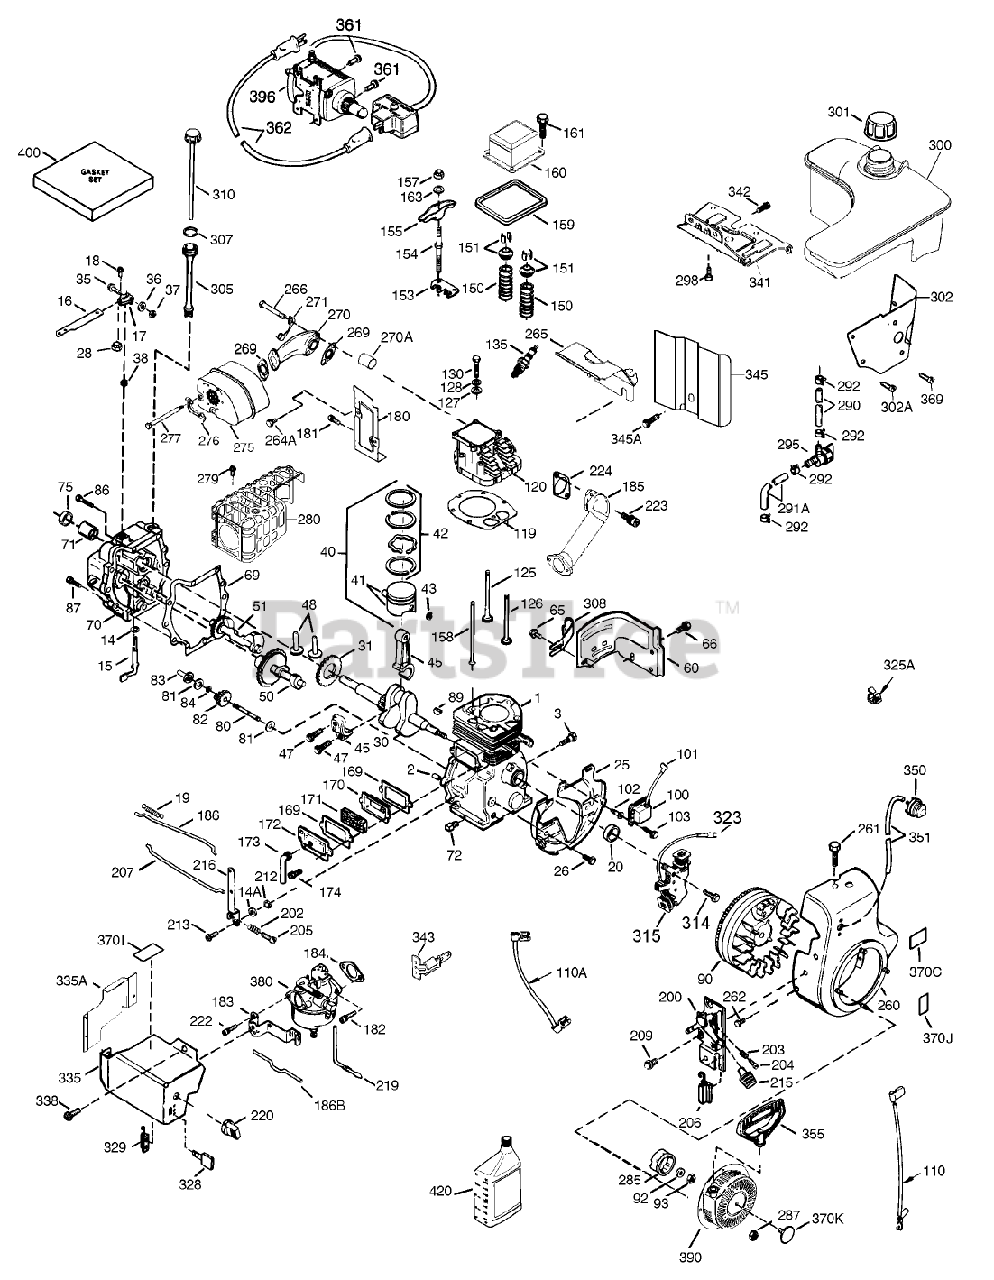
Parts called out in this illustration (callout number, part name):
1	Cylinder (Incl. 2, 20, 72 80)
2	Pin-Dowel
3	Screw (1/4-20x1/2)
14	Washer-Flat
14A	Washer
15	Governor Rod (Incl. Ref.#14 38)
16	Governor Lever
17	Clamp-Lever, Governor
18	Screw (T-15, 8-32x7/16)
19	Throttle Spring
20	Seal-Oil
25	Baffle-Housing, Blower
26	Screw (1/4-20x19/32)
28	Nut-Lock
30	Crankshaft
31	Counterbalance Gear
35	Screw
36	Washer-Lock
37	Nut-Lock
38	Ring-Retaining
40	Piston Pin and Ring ASM (STD)
40	Piston Pin and Ring ASM (.010)
40	Piston Pin and Ring ASM (.020)
41	Piston Pin Ass-y(Std.)(Incl. 43)
41	Piston Pin Ass-y (.010" OS)(Incl. 43)
41	Piston Pin Ass-y.(.020" OS)(Incl. 43)
42	Ring Set (STD)
42	Ring Set (.010)
42	Ring Set (.020)
43	Retaining Ring-Piston Pin
45	Connecting Rod ASM (Incl. Ref. #47)
47	Bolt-Rod, Connecting
48	Lifter-Valve
50	Camshaft
51	Counterbalance Weight
60	Extension-Housing, Blower
65	Screw (10-24 x 9/16)
66	Screw
69	55072/75/86/89 TWO
70	Cylinder Cover (Incl. Ref. #14, 15, 38, 71, 75)
71	2025A77 WIZARD ROTA
72	Plug-Drain, Oil (SQH 1/4-18)
75	Seal-Oil
80	Governor Shaft
81	Washer
82	Gear-Asm Governor
83	Governor Spool
84	Ring-Retaining
86	Screw (1/4-20x1-3/16)
87	Screw (1/4-20x1-11/16)
89	Key-Flywheel
90	Flywheel ASM
92	Washer-Belleville
93	Nut-Flywheel
100	Solid State ASM
101	Cover-Spark Plug
102	Stud-Mounting, Solid State
103	Screw (T-15, 10-24 x 15/16)
110	Wire-Ground
110A	Wire-Ground
119	Cylinder Head Gasket
120	Cylinder Head
125	Valve-Exhaust (STD)
125	Valve-Exhaust (1/32)
126	Valve-Intake (STD)
126	Intake Valve (1/32)
127	Washer-Flat
128	Washer-Belleville
130	Screw (5/16-18 X 2-1/2)
135	Spark Plug-Resistor (R N 4C)
150	Spring-Valve
151	Keeper-Spring, Valve
153	Guide-Rod, Push
154	Stud-Arm, Rocker
155	Arm-Rocker
157	Nut-Jam
158	Rod-Push
159	Gasket-Cover, Rocker Arm
160	Cover-Arm, Rocker
161	Screw
163	Washer
169	Gasket-Cover, Valve
170	Body-Breather
171	Element-Breather
172	Cover-Valve
173	Tube-Breather
174	Screw
180	Extension-Housing, Blower
181	Screw (10-24 x 9/16)
182	Screw (T-30, 1/4-20 X 27-32)
183	Bracket-Choke
184	Gasket-Carburetor To Intake Pipe
185	Pipe-Intake
186	Governor Link
186B	Spring-Choke
200	Bracket-Control (Incl. Ref. #203, 204 and 206)
202	Compression Spring
203	Spring-Compression
204	Screw (T-10, 5-40x7/16)
205	Screw
206	Terminal
207	Choke Link
209	Screw (10-32 x 1/2)
212	Bushing
213	Screw
215	Knob-Control
216	Lever-Adjusting
219	Rod-Choke
220	Knob-Control
222	Screw (10-32 x 1/2)
223	Screw (T-30, 5/16-18 X 7/8)
224	Gasket-Pipe
260	Blower Housing
261	Screw (1/4-20 X 5/8)
262	Screw
264A	Screw
265	Cover-Head, Cylinder
266	Screw (5/16-18 X 1-9/32)
269	Gasket-Manifold, Exhaust
270	55107 SNWTHWR ATTCH
270A	Liner-Port, Exhaust
271	Plate-Locking
275	Muffler
276	Locking Plate
277	Screw (5/16-18 X 4-1/2)
279	Screw
280	Cylinder (Incl. 2, 20 150)
285	Cup-Starter
287	Nut and Lock Washer (1/4-28)
290	Line-Fuel
291A	Line-Fuel (8.62)
292	Clamp-Line, Fuel
295	Valve-Shut Off, Fuel
298	Screw (1/4-15x7/8)
300	Fuel Tank (Incl. 292 and 301)
301	Cap-Fuel
302	Extension-Tank, Fuel
302A	Screw (10-32 x 1/2)
305	Tube-Fill, Oil
307	O-Ring
308	Clip-Tube, Fill
310	Dipstick
314	Screw (1/4-20 x 3/4)
315	Coil-Alternator, 18 Watt (Includes 323)
323	Terminal
328	Key-Ignition
329	Terminal
335	Spring
335A	Cover-Carburetor
338	Screw (10-32 x 1/2)
341	Bracket-Tank, Fuel
342	Screw (5/16-18 X 7/8)
343	Bracket-Switch, Key
345	Baffle-Heat
345A	Screw (10-32 x 1/2)
350	Primer ASM
351	Line-Primer
355	Handle-Starter, Mitten Grip
361	Screw (T-30, 1/4-20x15/32)
362	Cord-Extension (10-6)
369	Screw (12-16 x 5/8)
370C	Decal-Primer, International Symbol
370I	Decal-Warning (Bilingual)
370J	Decal-Choke
370K	Decal-Tecumseh Logo for Top of Recoil Starter
380	Carburetor (Incl. Ref.# 184)
390	Starter-Rewind
396	Electric Starter Motor (120 Volt)
400	Gasket Set (Incl. Items Marked PK in Notes) Incl. part #-s 27272A (1), 27 896A (2), 33263 (1), 33515A (1), 34265 (1), 35317 (1), 35683 (1), 35762 (2), 35952 (1), 36333 (1), 36352 (1), 36358 (1), 36930 (1), 36932 (1), 36942 (1)
420	Oil-Engine, S A E 5W30
